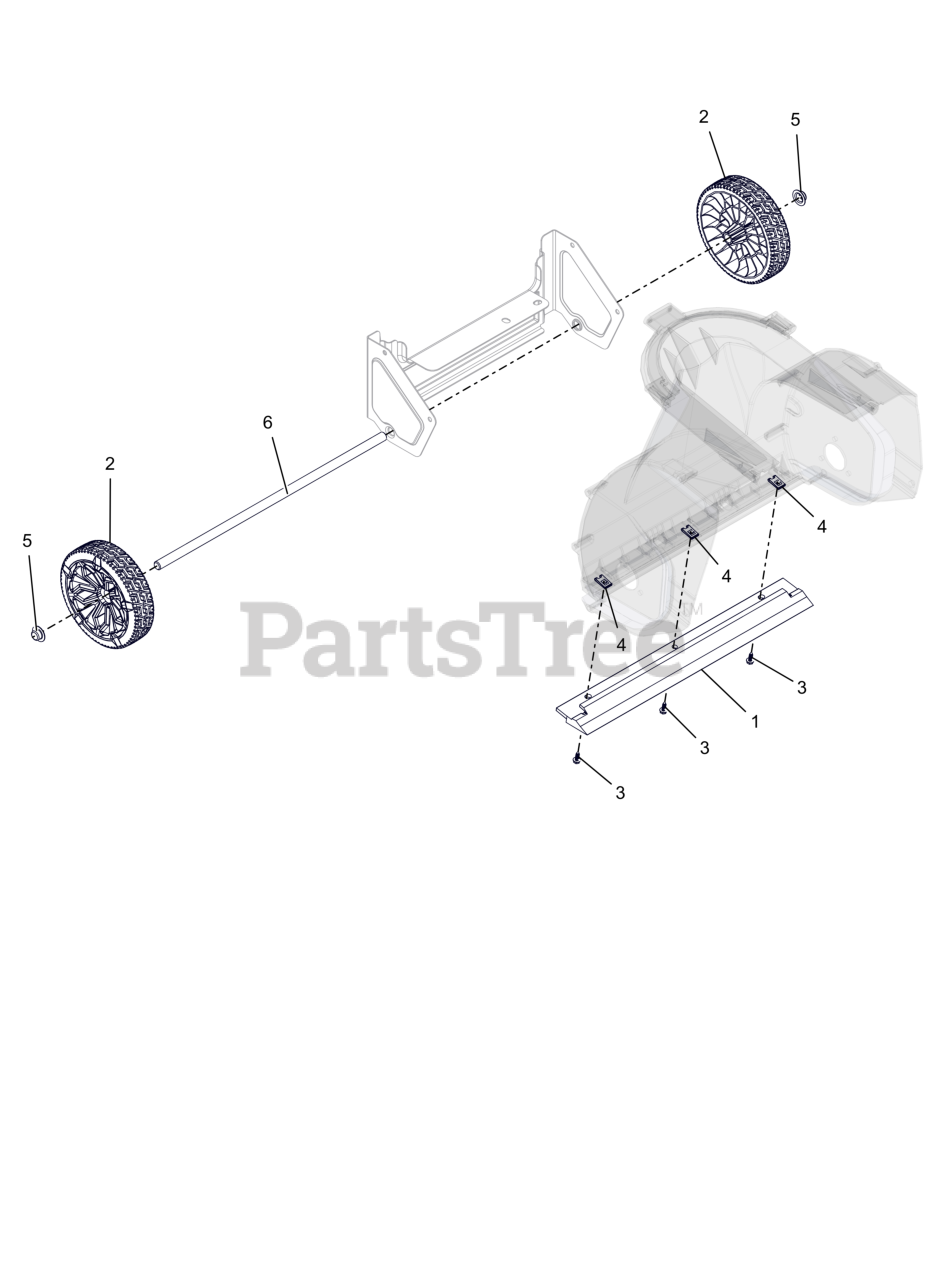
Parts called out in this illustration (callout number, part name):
1	KIT, SCRAPER REPLACEMENT 18IN
2	WHEEL, ASM
3	#10X5/8 SHEETMETAL SCR
4	NUT, CLIP ON - #10 NOSLIP
5	NUT, PUSH - AXLE
6	AXLE, WHEEL
